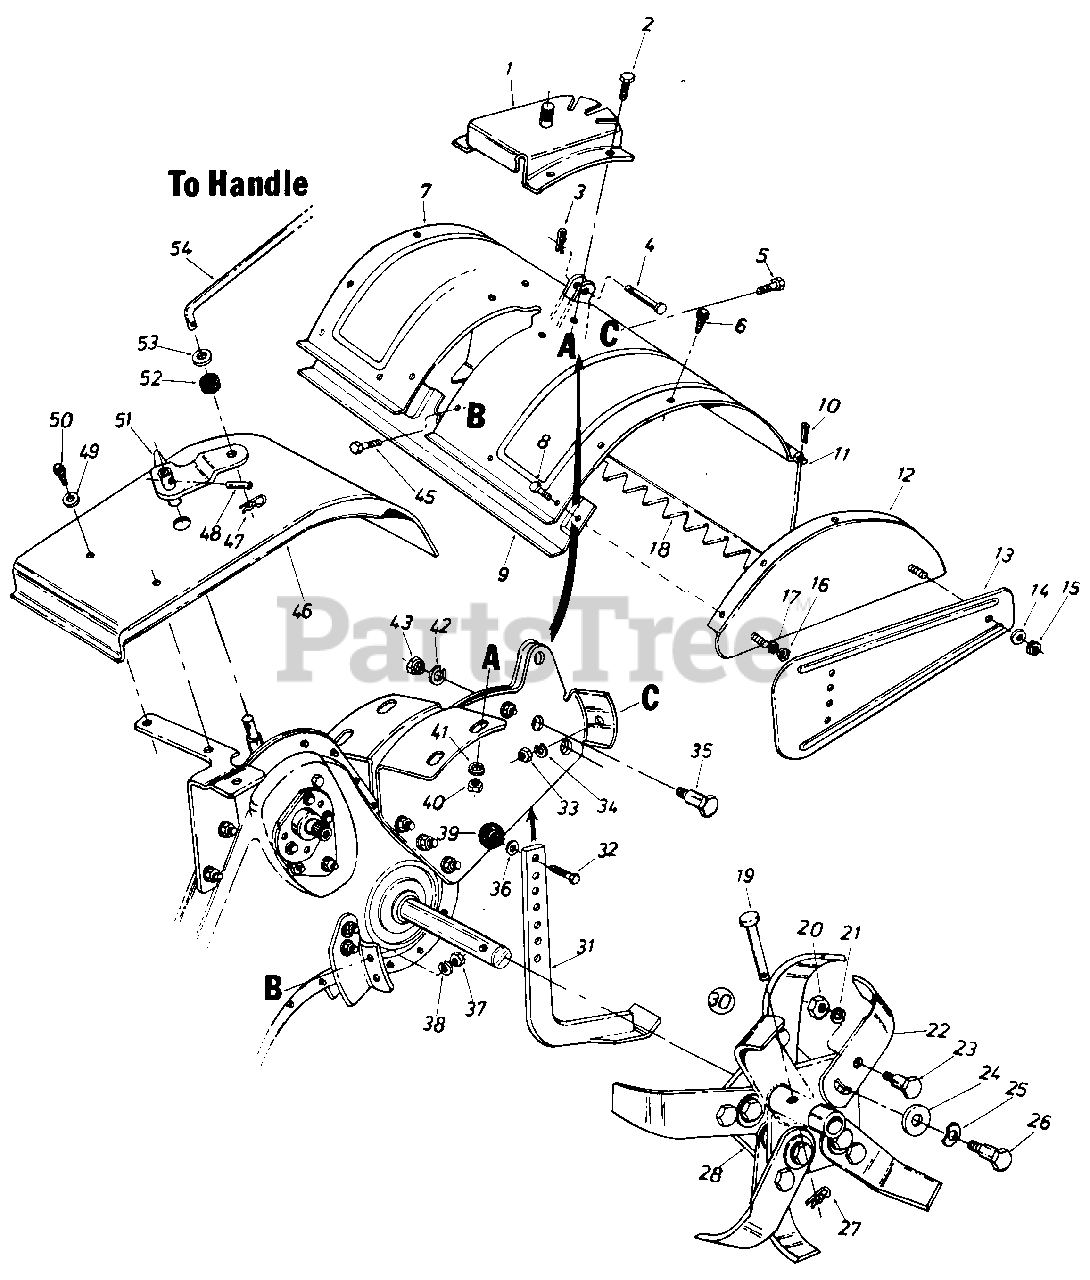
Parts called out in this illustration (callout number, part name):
1	Handle Positioner Brkt. Ass'y.
2	Hex Bolt 3/8-16 x .75" Lg.
3	Intern. Cotter Pin 5/16" Dia.
4	Clevis Pin .375" Dia.
5	Hex Bolt 5/16-18 x .75" Lg.
6	Hex Wash. Tap Scr.
9	Bracket Reinforcement 18"
10	Cotter Pin 3/32" Dia. x .75" Lg.
11	Tiller Flap Rod
15	Hex Nut 5/16-18 Thd.
16	Hex Nut 5/16-18 Thd.
17	L-Wash. 5/16" I.D.
19	Clevis Pin .375" Dia.
20	Hex Nut 3/8-24 Thd.
21	L-Wash. 3/8" I.D. H.D.
23	Shld. Bolt 1/2" Dia. x .175
24	Fl-Wash. .51" I.D. x 1.50" O.D.
25	Bell-Wash. .515" I.D. x 1.14" O.D.
26	Shld. Bolt 1/2" Dia. x .320
27	Intern. Cotter Pin
32	Hex Bolt 3/8-16 x .75" Lg.
33	Hex Nut 5/16-18 Thd.
34	L-Wash. 5/16" I.D.
35	Shld. Bolt 1/2" I.D. x .62" Lg.
36	Fl-Wash. 3/8" I.D. x 518" O.D.
37	Hex Nut 5/16-18 Thd.
38	L-Wash. 5/16" I.D.
39	Ball Knob
40	Hex Nut 3/8-16 Thd.
41	L-Wash. 3/8" I.D.
42	L-Wash. 3/8" I.D.
43	Hex Nut 3/8-16 Thd.
45	Hex Bolt 5/16-18 x .75" Lg.
46	Shift Cover
47	Intern. Cotter Pin 5/16" Dia.
48	Spring Roll Pin 3/16" Dia. x 1.00" Lg.
49	Fl-Wash. .281" I.D. x .62" O.D.
50	Hex Wash. Self-Tap Scr. 1/4-20 x .50" Lg.
51	Shifting Crank Ass'y. D x 2.05
52	Rubber Washer .33" I.D. x .87" O.D.
53	Fl-Wash. .400" I.D. x 1.250" O.D.
54	Control Rod .33" Dia. x 37" Lg.
